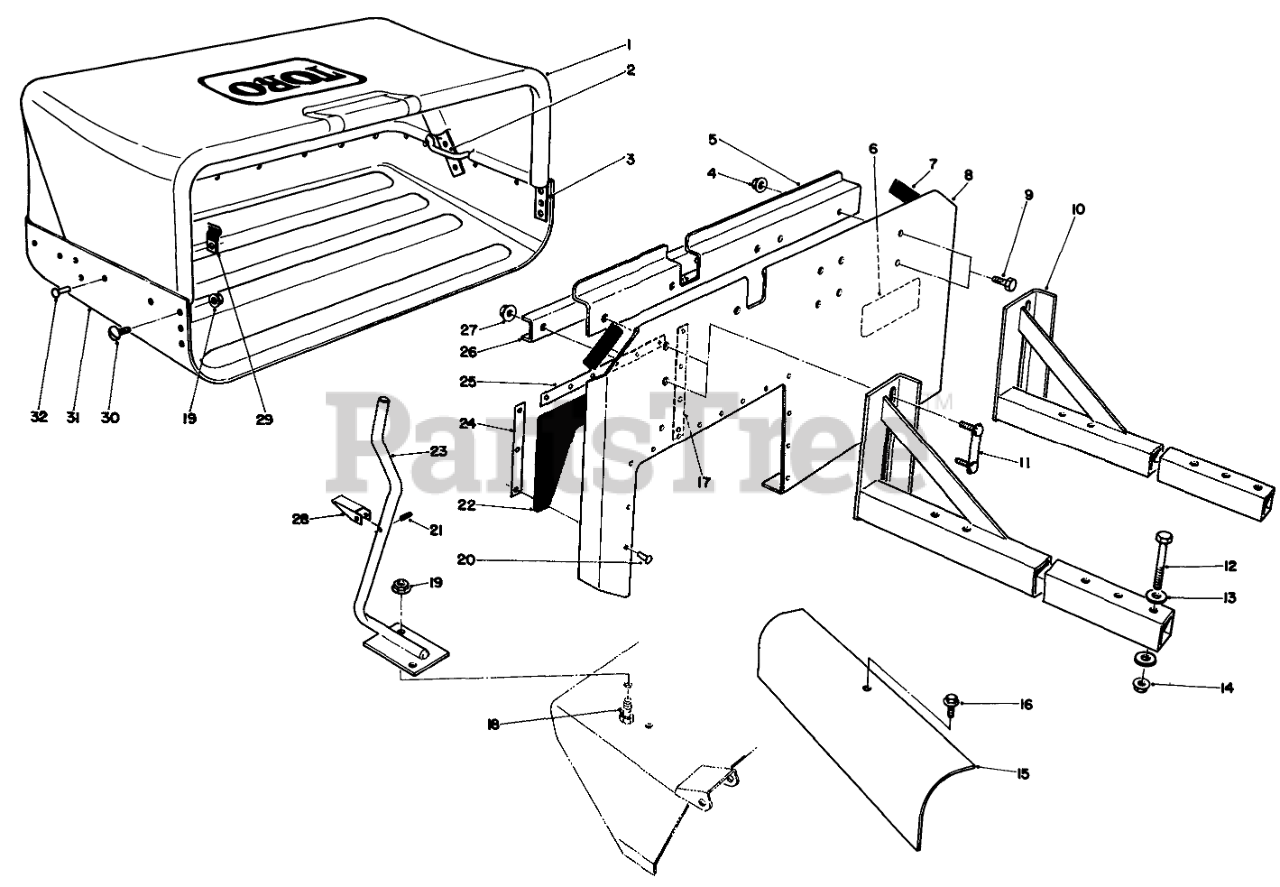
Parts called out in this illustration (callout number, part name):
1	Bag-Cloth
2	Rod-Cloth
3	Tube-Bag Support
4	NUT-HHF, WHIZ
5	Support-Bag
6	DECAL-DANGER
7	PAD-RUBBER
8	Panel-Back
9	SCREW-HH
10	Beam-Mounting
11	Retainer-Bolt
12	SCREW-HH
13	WASHER-FLAT
14	NUT-LOCK, NI
15	Baffle-44in
16	Screw-HH
17	STRIP-Seal, 10in
18	SCREW-HH
19	NUT-HF
20	RIVET-POP
21	PIN-SPRING
22	Seal-Panel Model 30126
23	Rod-Lockup
24	STRIP
25	STRIP-SEAL, 16in
26	Support-Channel
27	NUT-LOCK, FLANGE
28	LATCH-LOCKUP
29	CLIP-HALF
30	SCREW-PPH
31	TRAY-BAG, GRASS
32	RIVET-BLIND
